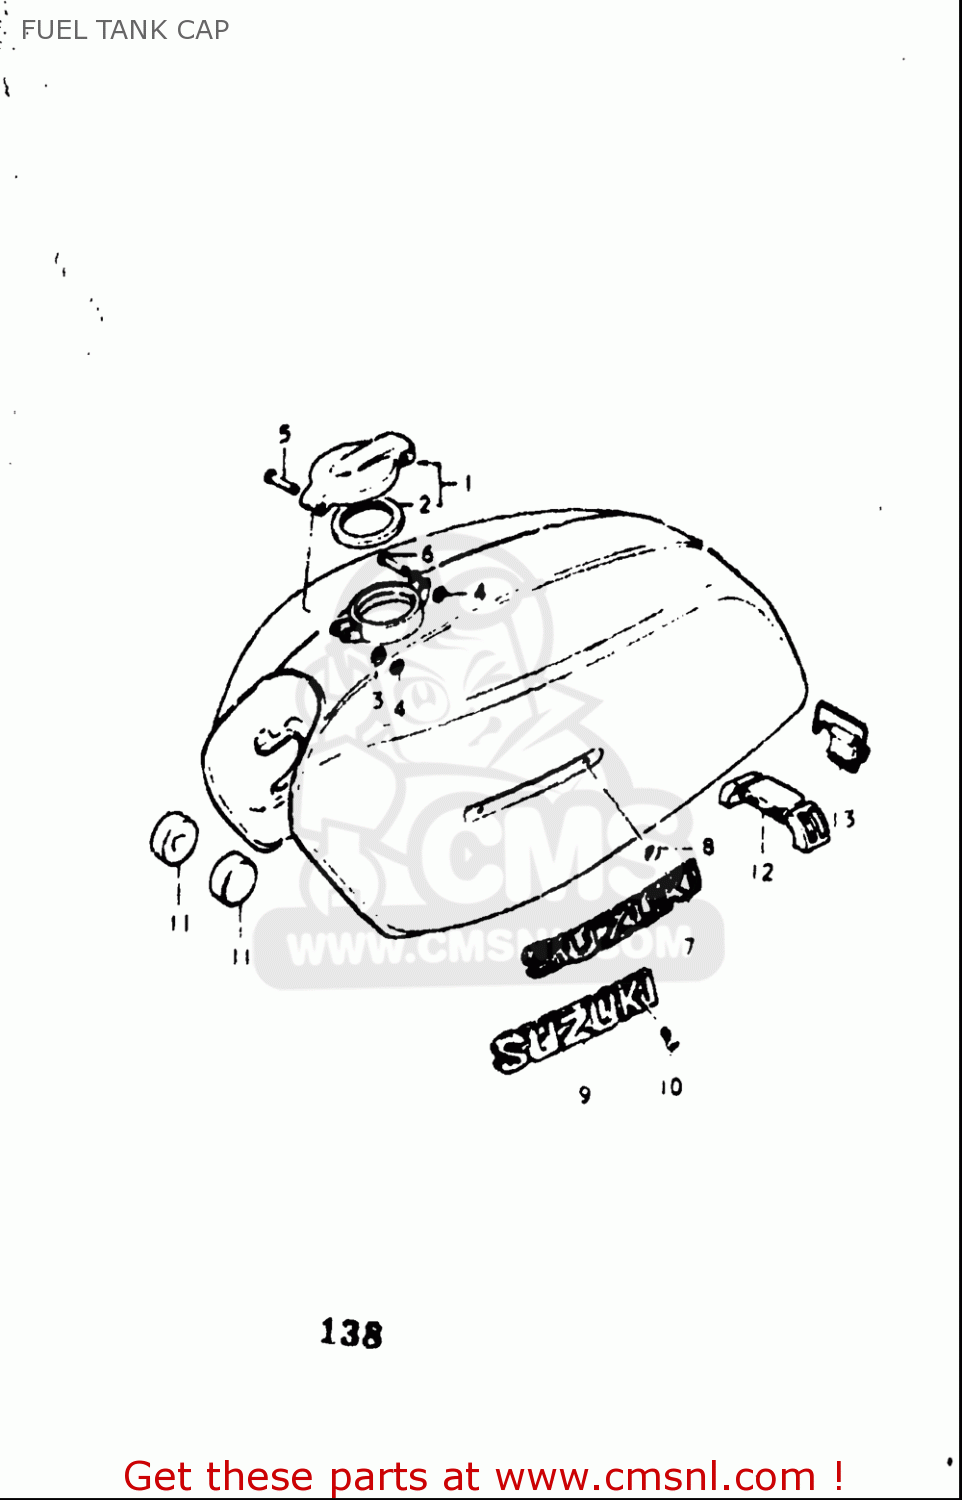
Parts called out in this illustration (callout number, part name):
1	CAP ASSY,FUEL TANK
2	GASKET (NAS)
3	WASHER
4	E RING
7	EMBLEM
8	NUT
9	EMBLEM,FUEL TANK
10	SCREW
11	CUSHION
12	CUSHION
13	BAND
